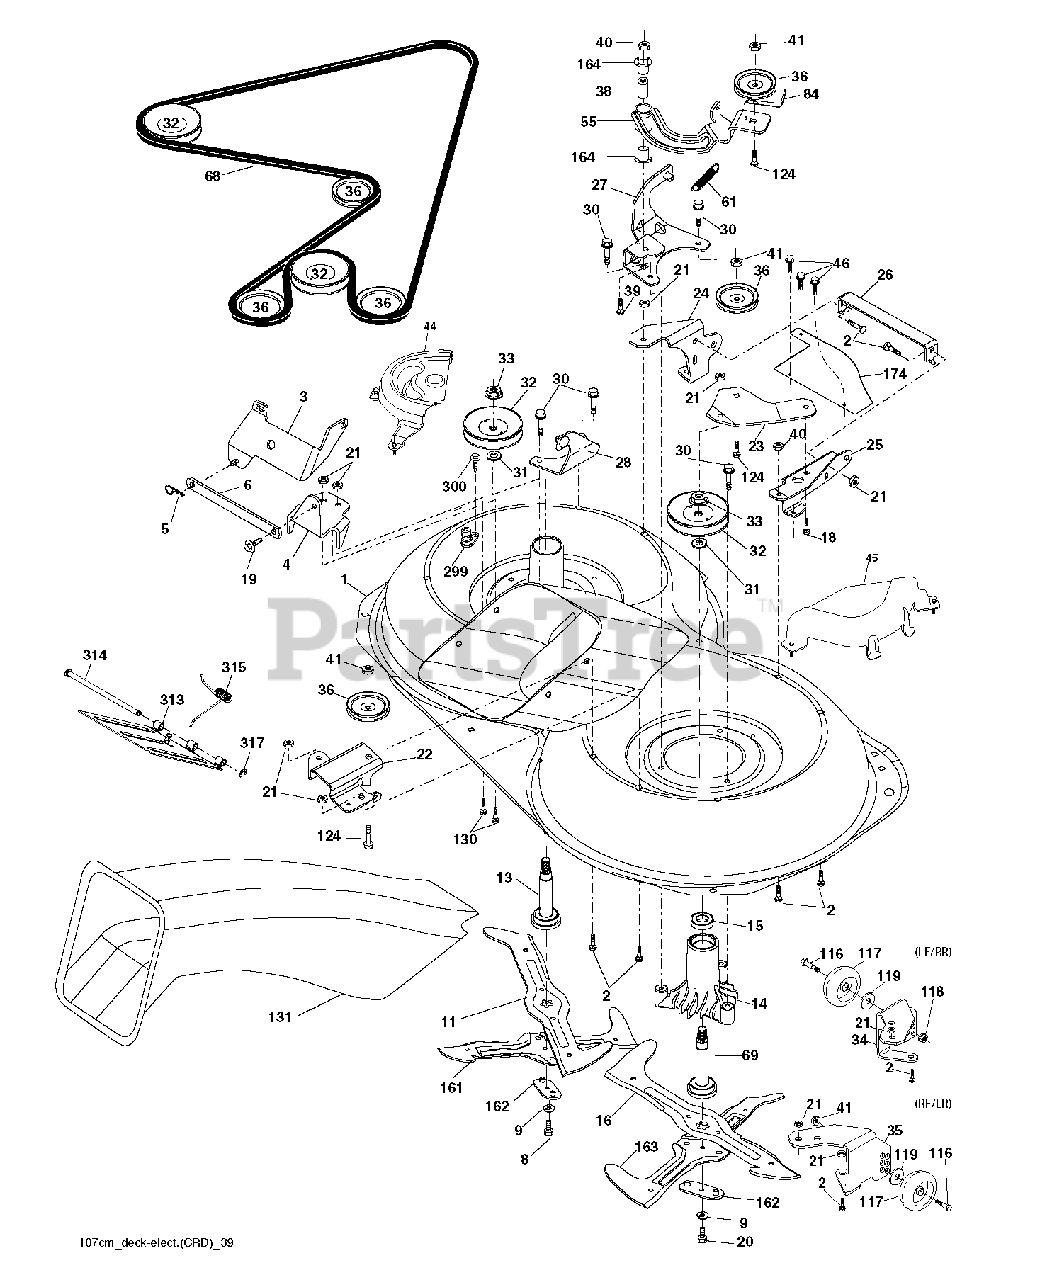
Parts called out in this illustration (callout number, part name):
2	BOLT 5/16-18 X3/4 ZN/YEL GR 5
3	BRACKET.ASM.BAR.SWAY.CHASS
5	Retainer Spring
6	BAR.SWAY.92.CRD
8	BOLT.3/8-24X1.25 GR8
9	LOCKWASHER
11	BLADE.3N1.LH.CRD
13	SHAFT ASM VENT
14	HOUSING.MANDREL.VENTED (MACHD)
16	BLADE.3N1.RH.CRD
19	BOLT SHD 5/16-18
20	BOLT.3/8-24X1.25GR8. LHTHRD
21	LOCKNUT
22	BRACKET.IDLER.RR.107.CRD
24	BRACKET
25	BRACKET RF
26	SUPPORT
28	BRACKET
30	SCREW, WASHER HEAD
31	WASHER.SPACER.MANDREL
32	PULLEY.MANDREL.4.80 PD.2006
33	NUT.FLANGE.LOCK.TOP
34	BRACKET
35	BRACKET
36	PULLEY.IDLER.4.25
41	NUT LOCK FLG 3/8-16 UNC
44	COVER MANDREL LEFT
45	COVER MANDREL RIGHT
46	SCREW.1/4-20X5/8
55	ARM.IDLER.107.CRD
61	SPRING
68	HEX-BELT 107 MOWER
69	SHAFT.ASM.W/LWR.BRG.RH.THREAD
84	KEEPER, BELT IDLER
116	BOLT.SHOULDER.3/8-16X3-5/8.
117	WHEEL. GUAGE RALLY
118	NUT LOCK FLG 3/8-16 UNC
119	WASHER
124	BOLT.3/8-16X1.50
130	BOLT.CARR.SQNK.5/16-18UNC.X3/4
163	BLADE.CROSS.RH.CRD.107
164	BRNG T
174	PLATE
299	PORT.WASHOUT
300	SCREW.TT.#10-32X.5.3/8.FLANGE
313	COVER DOOR.107 CM CRD EZ MULCH
314	PIN PIN.HINGE
317	E-RING.5/16"
